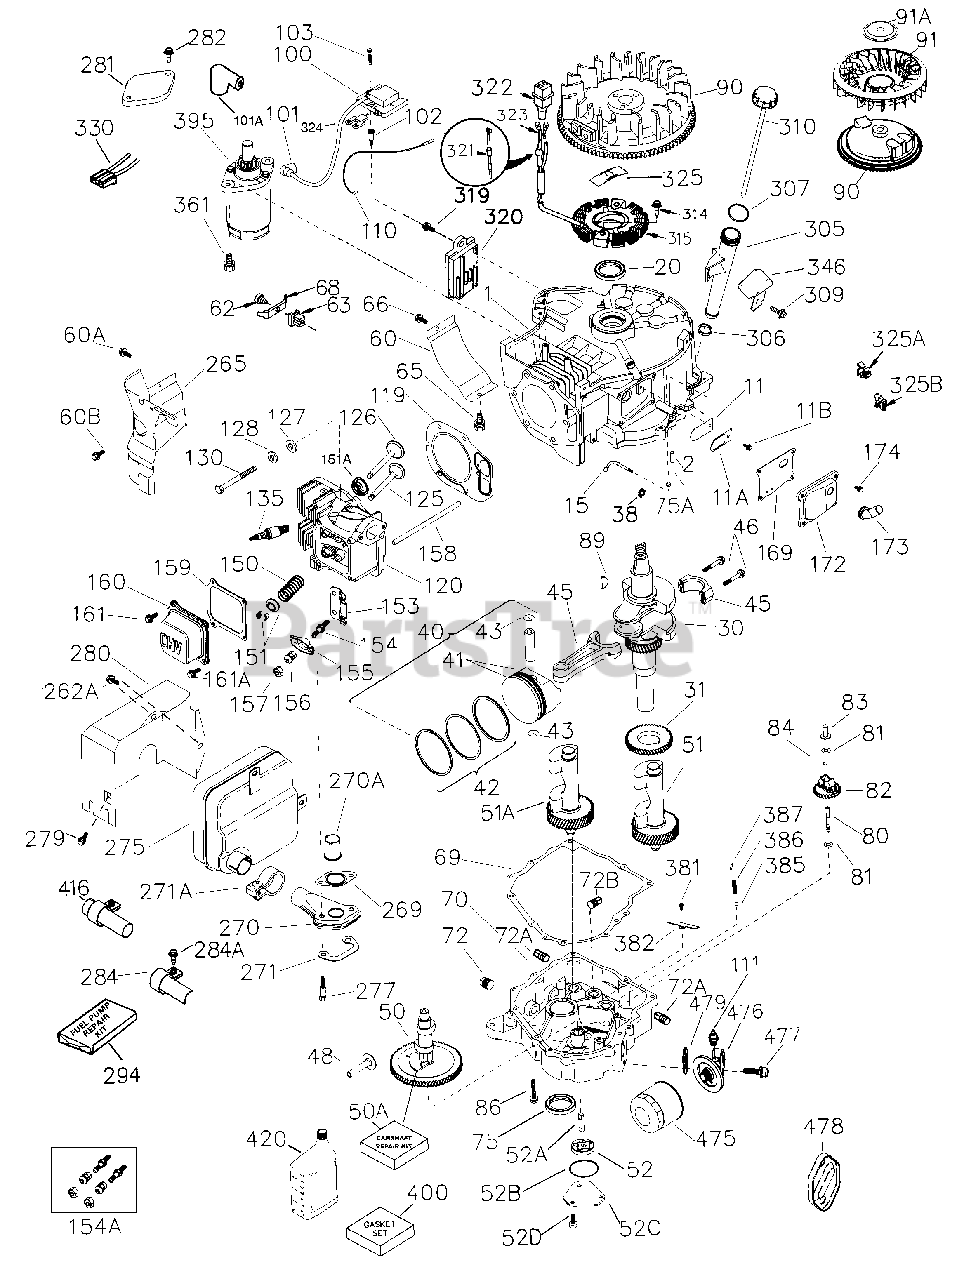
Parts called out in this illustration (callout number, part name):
1	"Cylinder (Incl. 2,11B,20,72B & 314)
2	Dowel Pin
11	Check Valve
11A	Breather Plate
15	Governor Rod
20	Oil Seal
30	Crankshaft
31	Counterbalance Gear
38	Retaining Ring
40	Piston, Pin & Ring Set (Std.)
40	Piston, Pin & Ring Set (.010" OS)
40	Piston, Pin & Ring Set (.020" OS)
41	Piston & Pin Ass'y. (Std.) (Incl. 43)
41	Piston & Pin Ass'y. (.010" OS) Incl. 43
41	Piston & Pin Ass'y. (.020" OS) Incl. 43
42	Ring Set (Std.)
42	Ring Set (.010" OS)
42	Ring Set (.020" OS)
43	Piston Pin Retaining Ring
45	Connecting Rod Ass'y. (Incl. 46)
45	Connecting Rod Ass'y. (.010" US) Incl . 46
45	Connecting Rod Ass'y. (.020" US) Incl . 46
46	Connecting Rod Bolts
48	Valve Lifter
50	Camshaft (MCR)
50A	Camshaft Repair Kit
51	Counterbalance Weight
52	Oil Pump Assembly
52A	Oil Pump Shaft
52B	* "O" Ring
52C	Oil Pump Cover (Incl. 52B)
52D	Screw, T-30, 1/4-20 x 43/64"
60	Air Baffle
60B	Screw, 10-24 x 1/2"
69	* Mounting Flange Gasket
70	Mounting Flange (Incl. 72, 72A, 75, 8 0, 381 thru 387) 81-387)
72A	Oil Drain Plug (3/8-18)
72B	Oil Drain Plug
80	Governor Shaft
81	Washer
82	Governor Gear Ass'y.
83	Governor Spool
84	Retaining Ring
86	Screw, 1/4-20 x 1-15/32"
89	Flywheel Key
90	Flywheel (W/Ring Gear)
91	Flywheel Fan
91A	Flywheel Retainer
100	Solid State Ignition (Incl. 101)
101	Spark Plug Cover
102	Solid State Mounting Stud
103	Screw, T-15, 10-24 x 15/16"
103	Screw, T-30, 5/16-18 x 1-7/16"
110	Ground Wire
119	* Cylinder Head Gasket
120	Cylinder Head (Incl. 119 & 151A)
125	Exhaust Valve (Std.)
125	Exhaust Valve (1/32" OS)
126	Intake Valve (Std.)
128	Belleville Washer
130	Screw, 5/16-18 x 2-45/64"
130A	Screw, 5/16-18 x 11/16"
130B	Screw, 1/4-20 x 1/2"
135	Resistor Spark Plug (RN4C) also avail able in Packaged Part #740069
150	Valve Spring
151	Valve Spring Keeper
151A	Intake Valve Seal
153	Push Rod Guide
154	Rocker Arm Stud
154A	Rocker Arm Stud/Bearing Kit (incl. re f. 155, 156, & 157)
155	Rocker Arm
157	Jam Nut, 5/16-24
158	Push Rod
159	* Rocker Arm Cover Gasket
160	Rocker Arm Housing
161	Screw, T-30, 1/4-20 x 1/2"
163	Rocker Arm Bearing
169	* Breather Gasket
172	Valve Cover
173	Breather Tube
243	Screw, 10-32 x 7/16"
264A	Screw, 1/4-20 x 5/8"
265	Cylinder Head Cover
266	Screw, 5/16-18 x 1-9/32"
269	* Exhaust Manifold Gasket
270	Exhaust Manifold
270A	Exhsust Port Liner
271	Locking Plate (Manifold)
271A	Muffler Clamp
275	Muffler
284	Exhaust Deflector & Clamp
305	Oil Fill Tube
306	* "O" Ring
307	"O" Ring
309	Screw, 1/4-20 x 57/64"
310	Dipstick
315	Alternator Coil (16 Amp DC) Incl. 322 & 323
322	Connector Body
323	Terminal
325	Wire Clip
325B	Wire Clip
361	Screw, 5/16-18 x 29/32"
365	Screw, 8-32 x 27/64"
382	Oil Strainer Screen
386	Pressure Relief Spring
387	Cotter Pin
395	Electric Starter Motor (12 Volt)
400	Gasket Set n notes)
406A	Solenoid Spring
420	SAE 30 4-Cycle Engine Oil (Quart)
475	Oil Filter (also available in Package d Part #740057B) also available in Pa ckaged Part #740057B
476	Oil Filter Adapter Kit Incl. 475,476& 477
477	Screw, T-30, 5/16-18 x 7/16
479	* Oil Filter Adapter Gasket
710	Compression Spring
711	Screw, 6-32 x 21/32"
